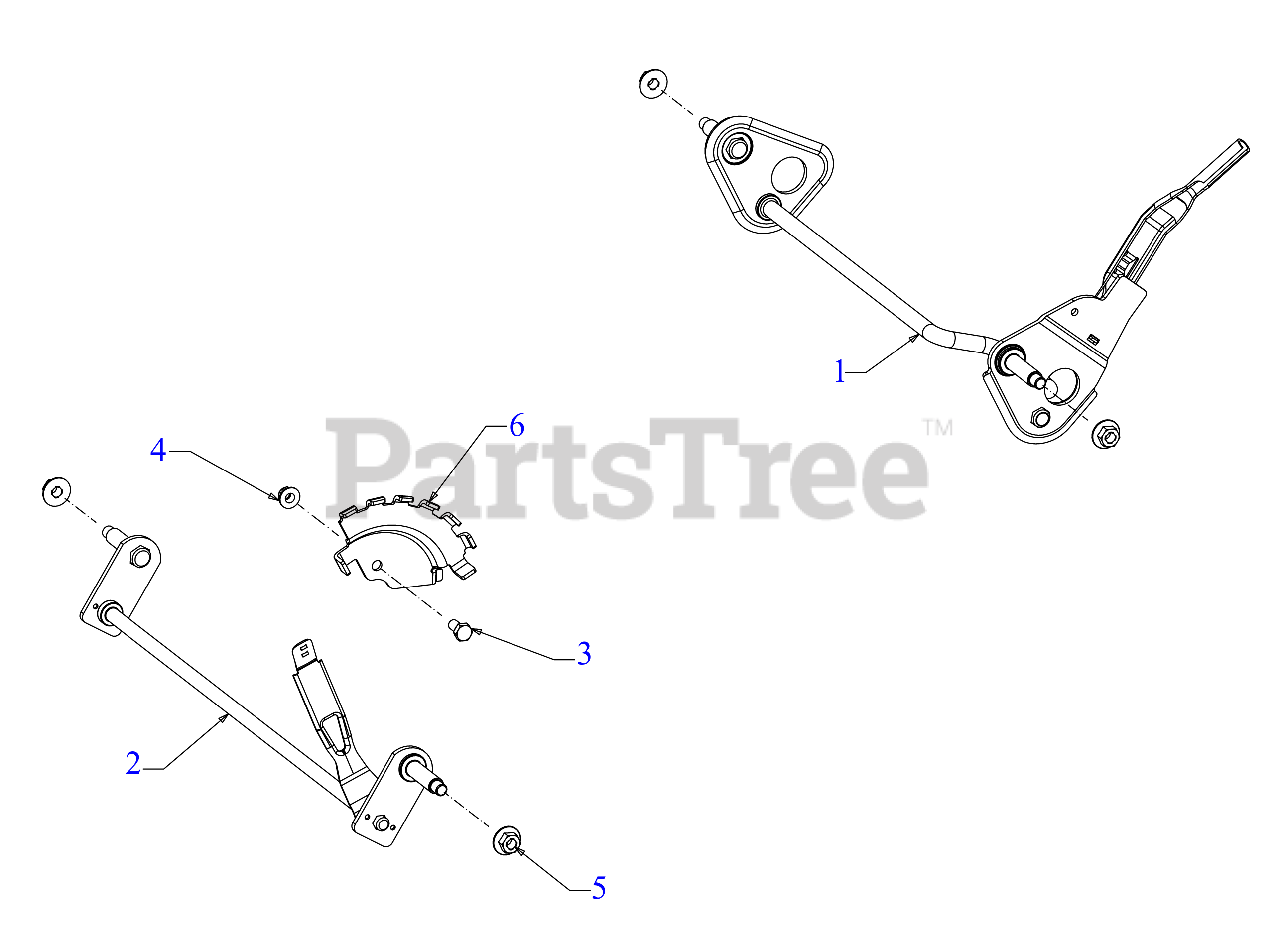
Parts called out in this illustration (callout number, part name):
1	AXLE (REAR) (w/HGT ADJUSTMENT)
2	AXLE (FRONT) (9" WHEEL)
3	SCREW 5/16-18X .625 GR5
4	FLANGE LOCK NUT 5/16-18
5	FLANGE LOCK NUT
6	23" HEIGHT ADJUSTMENT BRACKET(FRONT)
